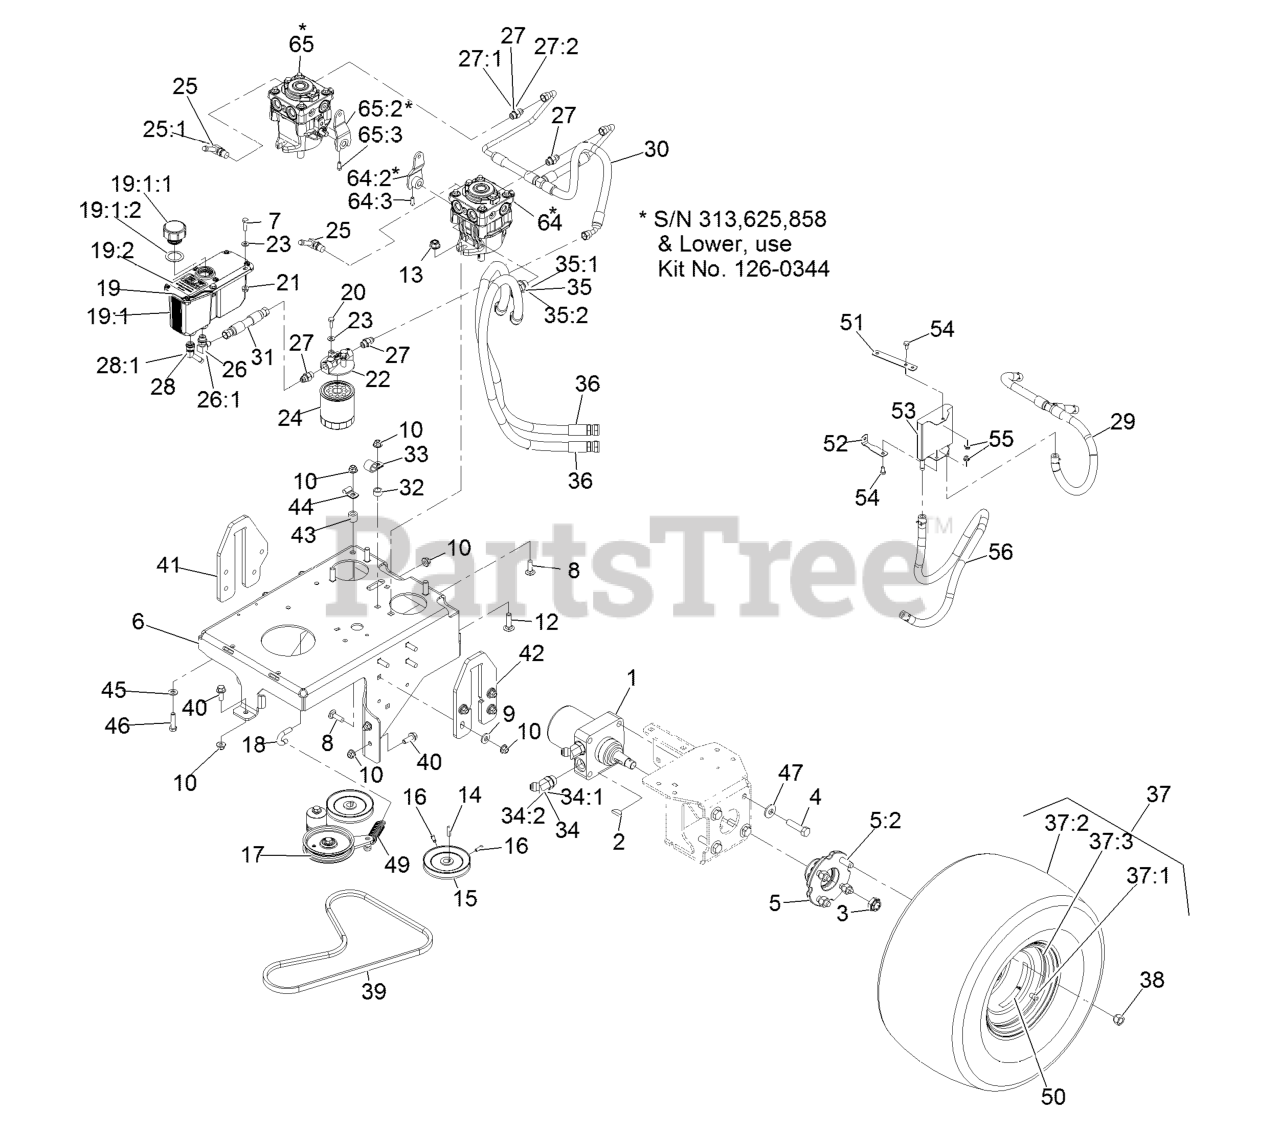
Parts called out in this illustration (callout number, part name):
1	MOTOR, WHEEL TE230
2	KEY-WOODRUFF
3	NUT-LOCK
4	SCREW-HH
5	WHEEL HUB ASM
5:2	STUD-TYPE, DRIVE
6	WELDMENT, FRAME
7	SCREW-HH
8	BOLT-CARR
9	WASHER-BELLEVILLE
10	NUT-HF, NI
12	SCREW-HH
13	NUT-HF, NI
15	PULLEY-PUMP
16	SCREW-SET
17	PUMP IDLER ASM
18	ANCHOR, SPRING
19	RESERVOIR ASM
19:1	Reservoir-Hyd
19:1:1	Cap-Reservoir, HYD
19:1:2	GASKET-CAP
19:2	DECAL-HYDRAULIC TANK
20	SCREW-HH
21	NUT-HHF
22	HEAD-FILTER
23	WASHER-FLAT
24	FILTER-25 MICRON, BI-DIRE
25	FITTING-ELBOW, 90
25:1	O-RING
26	FITTING-ELBOW, 90 DEG
27	FITTING-STRAIGHT
28	FITTING-BARBED, 45 DEG
28:1	O-RING
29	HOSE ASM-CASE DRAIN
30	HOSE ASSEMBLY - CHARGE
31	HYD HOSE ASM
32	SPACER-WHEEL
33	CLIP-LOOM
34	FITTING-HYD, 45 DEG
35	FITTING-HYD, 45 DEG
36	HYD HOSE ASM
37	WHEEL/TIRE ASM
37:1	RIM-8 INCH
37:3	Stem-Valve
38	NUT-LUG
39	BELT-V, LOWER PTO
40	SCREW-HHF 3/8-16 X 1
41	PLATE-LIFT, RH
42	PLATE, LIFT LH
44	CLIP-TUBE
45	WASHER-FLAT
46	SCREW-HH
47	WASHER-SPRING
49	SPRING-EXTENSION
51	BRKT-COOLER MOUNT, TOP
52	BRKT-COOLER MOUNT, BOTTOM
53	COOLER-OIL
54	SCREW-HH
56	HOSE ASM
64	PUMP W/ARM - LEFT
64:2	ARM-HYDRO
64:3	SCREW-SET
65	PUMP W/ARM -RIGHT
65:2	ARM-HYDRO
65:3	SCREW-SET
